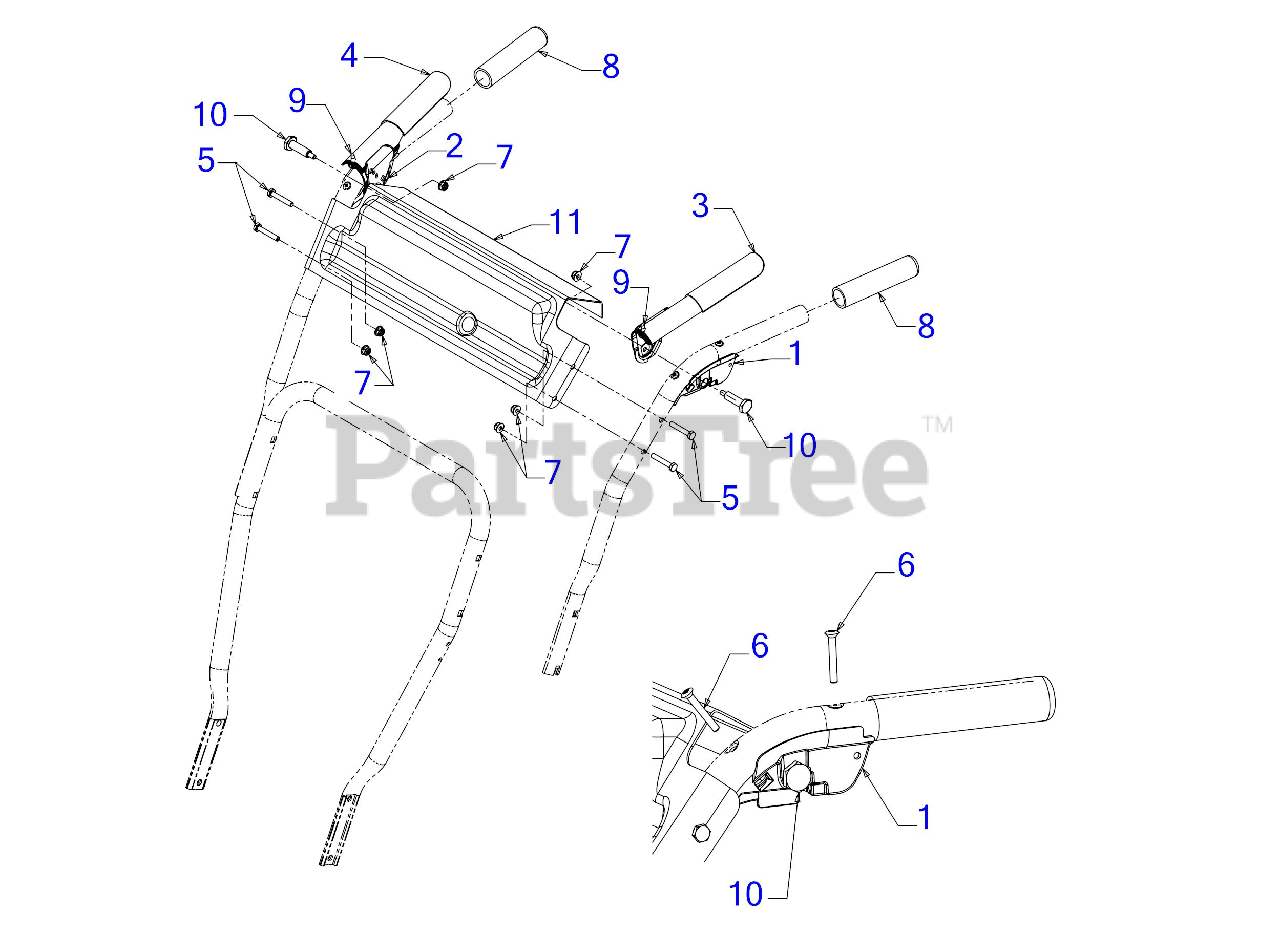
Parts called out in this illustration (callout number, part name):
1	CLUTCH LOCK HANDLE ASSEMBLY (LH)
2	CLUTCH LOCK HANDLE ASSEMBLY (RH)
3	HANDLE ASSEMBLY (LH)
4	HANDLE ASSEMBLY (RH)
5	SCREW 1/4-20 x 1.50 GR.5
6	SCREW #10-24 x 1.375
7	FLANGE LOCK NUT
9	RUBBER BUMPER
10	SHOULDER SCREW .437 x 1.345 1/4-20
11	HANDLE PANEL
